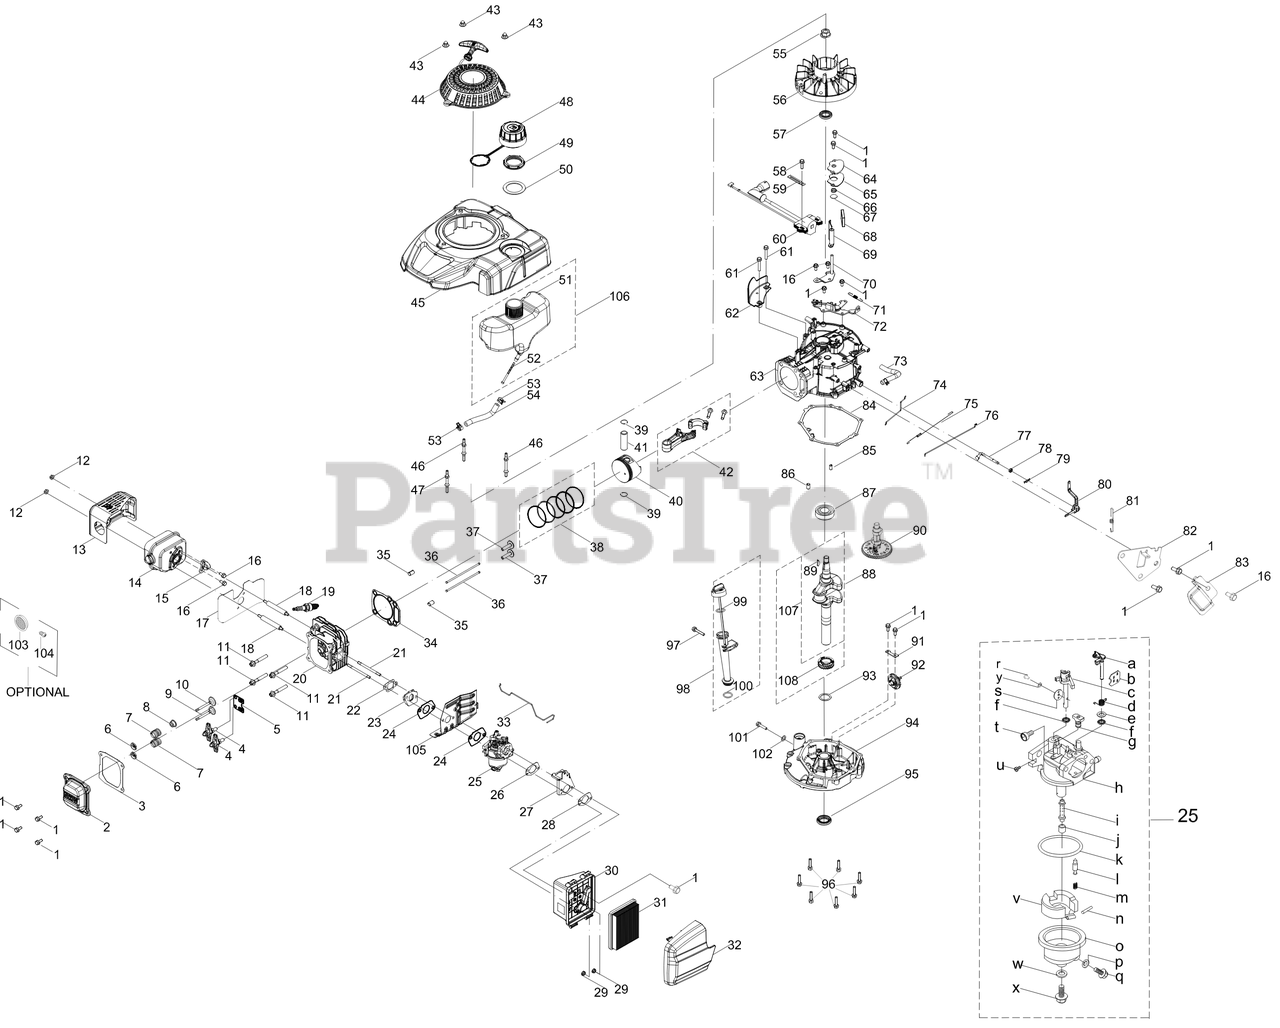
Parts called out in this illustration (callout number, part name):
1	BOLT M6-1 x 14 GR8.8
2	VALVE COVER
3	VALVE COVER GASKET
4	ROCKER ARM ASSEMBLY
5	PUSH ROD GUIDE
6	INTAKE VALVE SPRING RETAINER
7	VALVE SPRING
8	INTAKE VALVE SEAL
9	EXHAUST VALVE
10	INTAKE VALVE
11	SCREW M8 x 54 GR10
13	MUFFLER SHIELD
14	MUFFLER ASSEMBLY
15	THERMOSTAT
16	BOLT M6-1 x 12 GR8.8
17	MUFFLER GASKET
18	STUD M6-1 x 95
19	SPARK PLUG
20	CYLINDER HEAD
21	STUD M6 x 90
22	CARBURETOR INSULATOR GASKET
23	CARBURETOR INSULATOR
24	CARBURETOR GASKET
25	CARBURETOR ASSEMBLY HY-5X70A
26	AIR FILTER BRACKET GASKET
27	AIR FILTER BRACKET
28	AIR FILTER BASE GASKET
30	AIR FILTER HOUSING BASE
31	AIR FILTER
32	AIR FILTER COVER
33	TEMPERATURE CONTROL LINKAGE
34	CYLINDER HEAD GASKET
37	TAPPET
38	PISTON RING 4PC SET
39	PISTON PIN SNAP RING
40	PISTON ASSEMBLY
41	PISTON PIN
42	CONNECTING ROD ASSEMBLY
43	ACORN NUT
44	RECOIL STARTER ASSEMBLY
45	ENGINE SHROUD W/O IGNITION SWITCH
46	STARTER/SHROUD REAR STUD
47	STARTER/SHROUD FRONT STUD
48	FUEL CAP W/TETHER
49	FUEL TANK NUT
50	FUEL TANK UPPER GROMMET
51	FUEL TANK
52	FUEL FILTER
53	HOSE CLAMP
54	FUEL HOSE
55	FLYWHEEL NUT
56	FLYWHEEL
57	CRANKSHAFT SEAL
58	BOLT M6-1 x 20 GR8.8
59	FLEXIBLE CLAMP
60	IGNITION COIL ASSEMBLY
61	BOLT M6-1 x 25 GR8.8
62	ENGINE BRAKE COVER PLATE
63	CRANKCASE
64	BREATHER COVER PLATE
65	BREATHER GASKET
66	BREATHER VALVE SPRING
67	BREATHER VALVE
68	BREATHER SCREEN
69	AIR VANE
70	AIR VANE BRACKET
71	ENGINE BRAKE SPRING
72	ENGINE BRAKE ASSEMBLY
73	BREATHER HOSE ASSEMBLY
74	CHOKE LINKAGE
75	THROTTLE LINKAGE
76	THROTTLE SPRING
77	GOVERNOR ARM SHAFT
78	GOVERNOR SEAL
79	COTTER PIN
80	GOVERNOR ARM ASSEMBLY
81	GOVERNOR SPRING
82	COMPONENT BRACKET
83	GOVERNOR SHIELD
84	CRANKCASE COVER GASKET
85	DOWEL PIN
86	DOWEL PIN
88	CRANKSHAFT
89	FLYWHEEL KEY
90	CAMSHAFT
91	GOVERNOR GEAR MOUNTING PLATE
92	GOVERNOR GEAR/SHAFT ASSEMBLY
93	THRUST WASHER
94	CRANKCASE COVER
95	LOWER CRANKSHAFT OIL SEAL
96	BOLT-M6-1 x 28 GR8.8
97	BOLT M6-1 x 35 GR8.8
98	OIL DIPSTICK ASSEMBLY
99	O-RING
101	OIL DRAIN PLUG
102	WASHER
103	SPARK ARRESTOR
104	SCREW M3.5 x 9.5
105	CARBURETOR HEAT SHEILD
106	Fuel Tank Assembly
107	CRANKSHAFT ASSEMBLY
108	DRIVE TIMING GEAR
